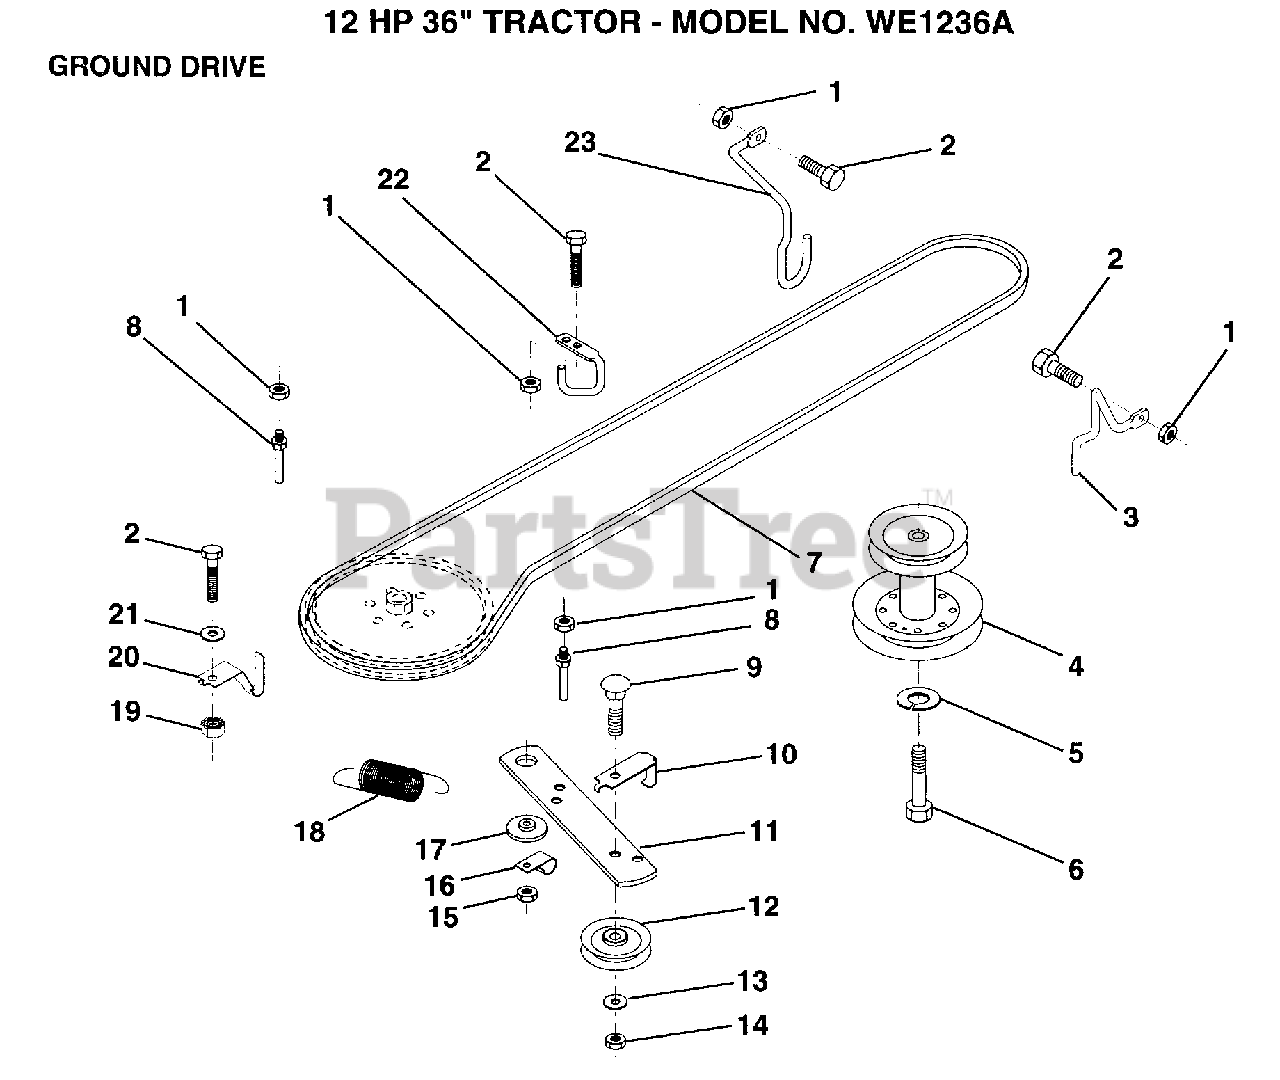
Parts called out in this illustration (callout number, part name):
1	NUT
2	BOLT
3	KEEPER RH
4	PULLEY.ENGINE.LR
5	LOCKWASHER
6	HEX BOLT
7	BELT
8	"KEEPER,DRIVE BELT"
9	BOLT
10	"KEEP,IDLER DR BEL"
11	ARM IDLER CLUT GD
12	PULLEY.IDLER.FLAT
13	WASHER
14	LOCKNUT
15	NUT
16	"CLIP,INSULATOR"
17	SPACER RETAINER
20	KEEPER.BELT.T/A
21	WASHER
22	"KEEPER,FRA DR BEL"
23	KEEPER MOWER LH
